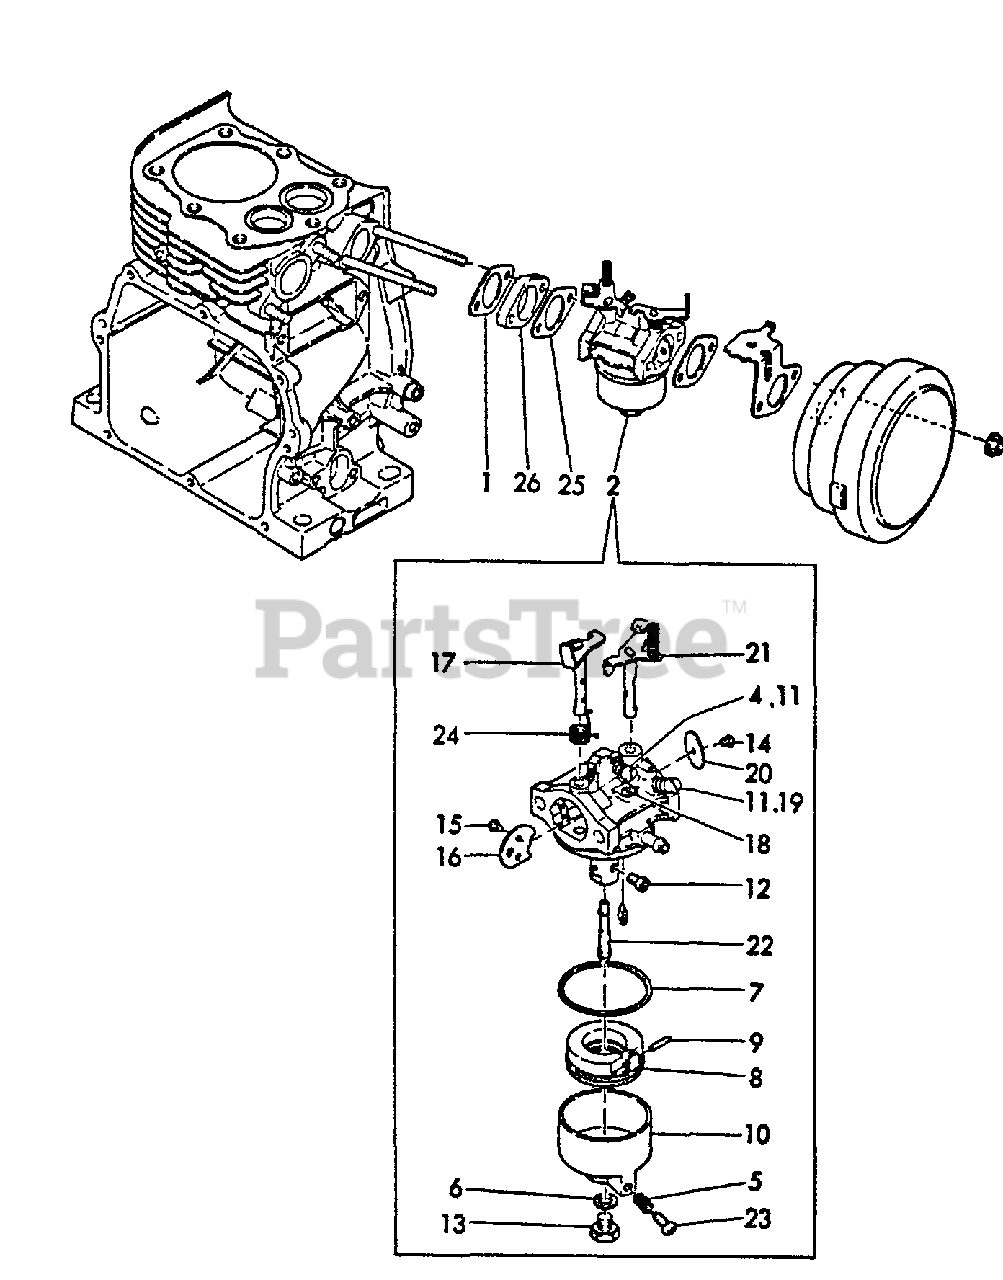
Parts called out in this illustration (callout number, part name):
1	GASKET, EXHAUST
2	CARBURETOR
4	SCREW, THROTTLE
6	WASHER
7	GASKET
8	FLOAT
9	PIN
10	BODY, FLOAT CHAMBER
11	SPRING
12	JET, MAIN
14	SCREW
16	VALVE, CHOKE
17	SHAFT, CHOKE
18	JET, PILOT
19	SCREW
20	VALVE, THROTTLE
21	SHAFT, THROTTLE
22	NOZZLE, MAIN
23	SCREW
24	SPRING
25	GASKET, INTAKE
26	INSULATOR, INTAKE
